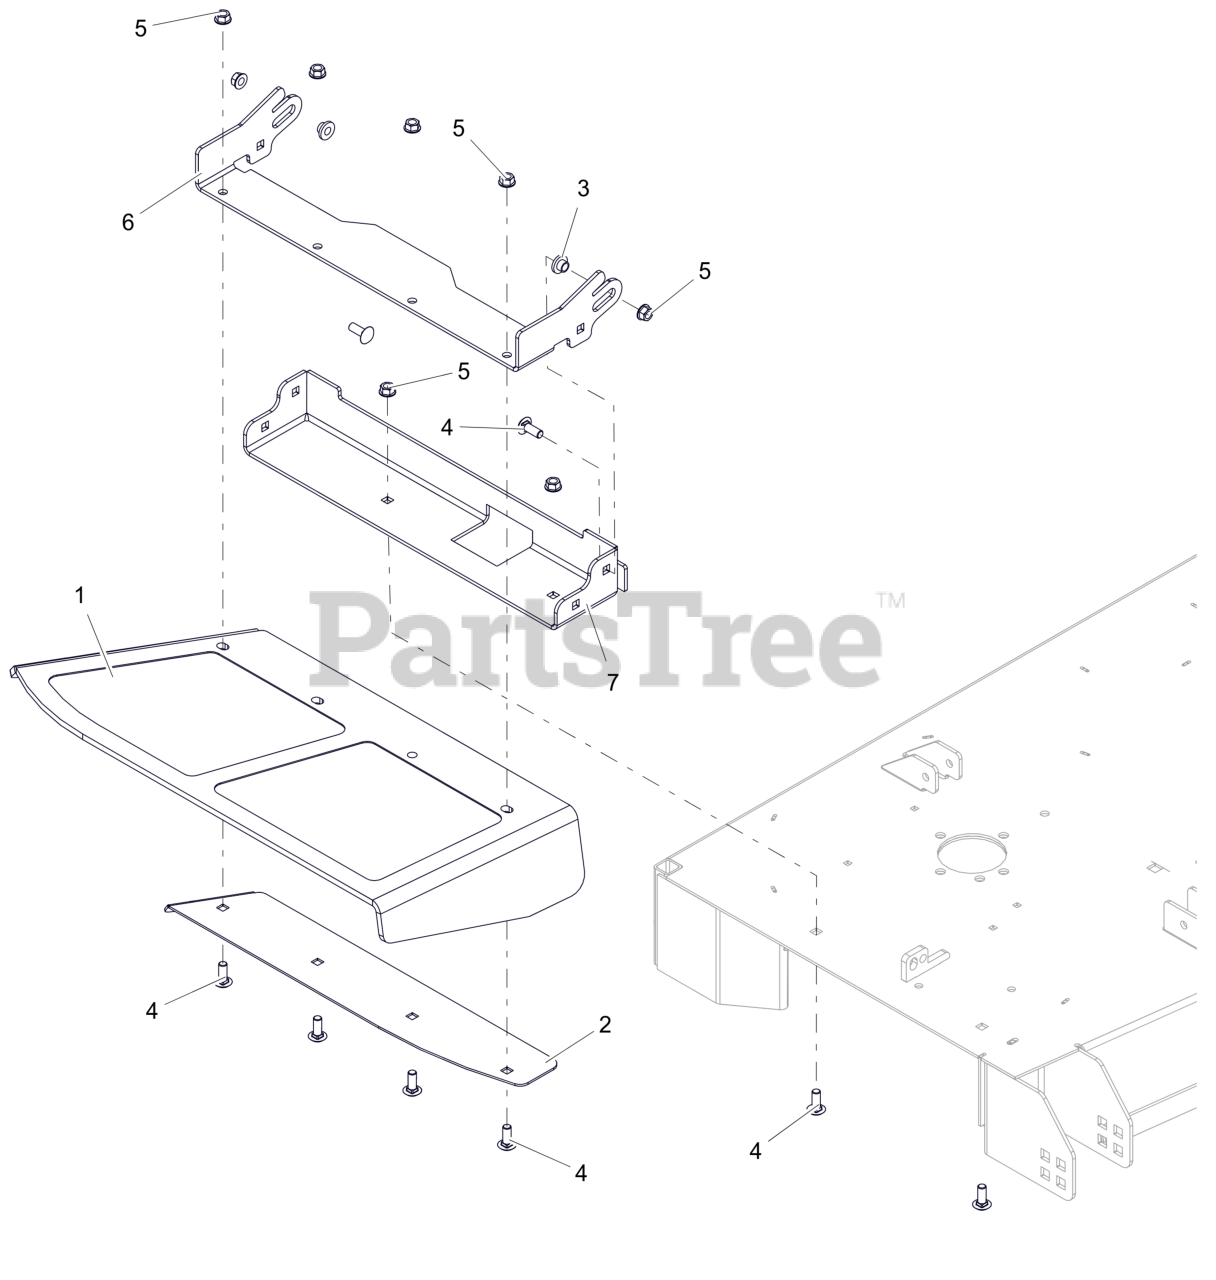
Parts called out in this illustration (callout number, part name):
1	CHUTE, FORMED RUBBER DISCH
2	DISCHARGE CHUTE CLAMP PLT -RED
3	BSHG-FLG .385X.500X.875X.406
4	BLT,RHSSN .38-16X1.00 G5 ZCC
5	NUT-LK-CTR-FLG .375-16 GF ZCC
6	BRKT, CHUTE MTG (RED)
7	BASE, DISCHARGE CHUTE MTG (RED) W/ SAFETY DECALS
